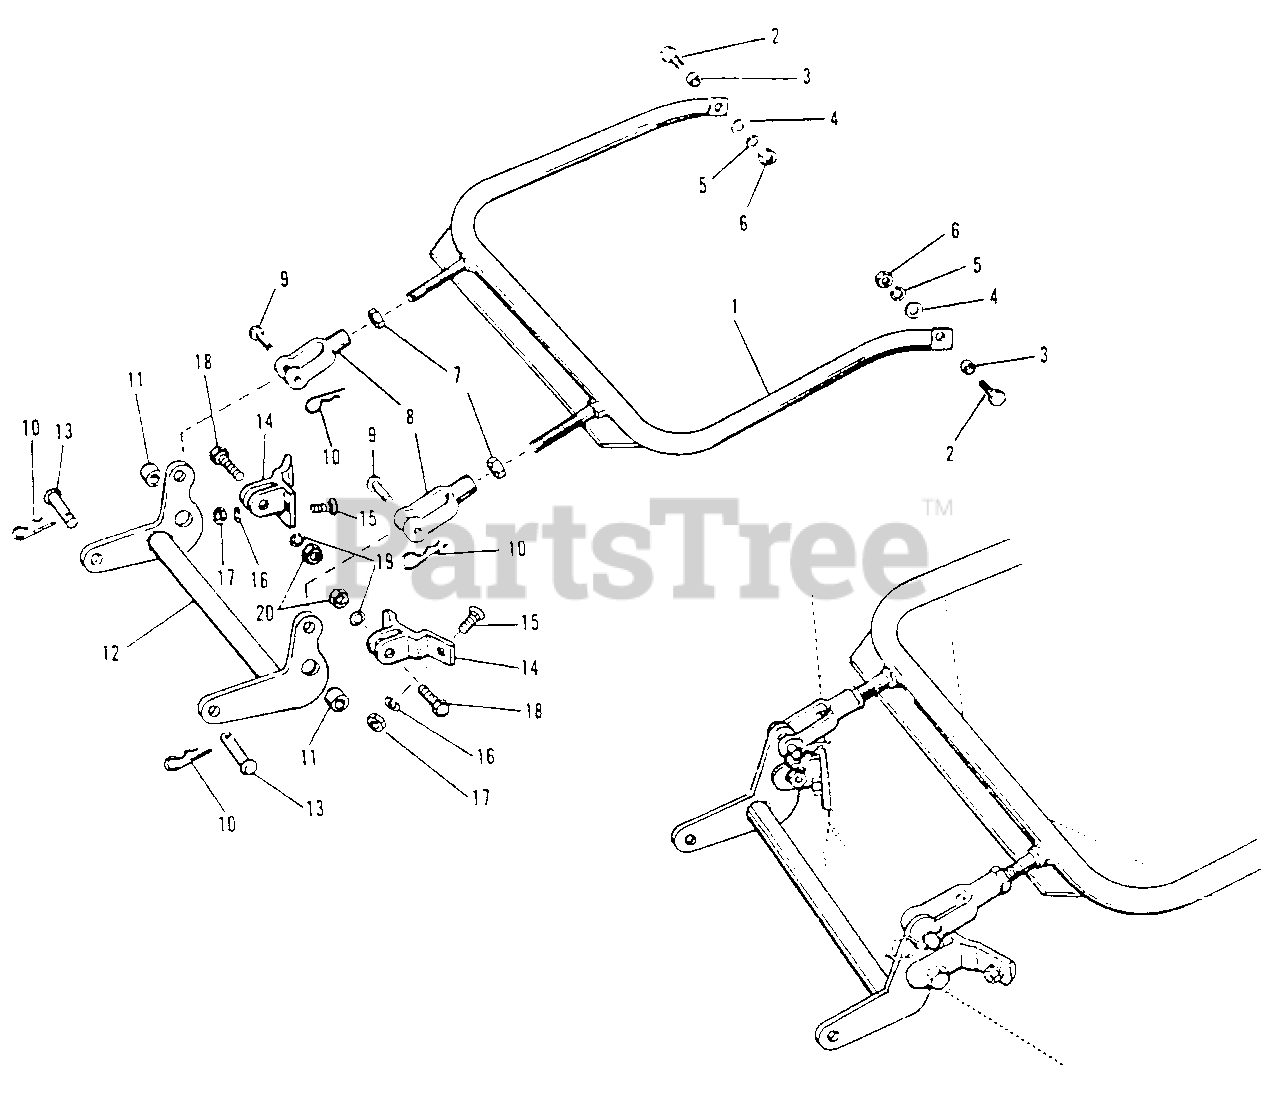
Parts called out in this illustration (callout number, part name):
1	Bail Assembly
2	Capscrew, Hex. Hd., 1/2"-13 NC x 1 1/4" lg.
4	Washer, Plain, 7/16
5	Washer, Lock, 1/2"
6	Nut, Hex., Full, 1/2"-13 NC
7	Nut, Hex., Jam, 1/2"-20 NF
8	Yoke End, Adjusting
10	Clip, Spring
12	Rocker Arm
13	Pin
14	Bracket Assembly, Front
15	Bolt, Carriage, 3/8"-16 NC x 1"
16	Washer, Lock, 3/8" .
17	Nut, Hex. Full, 3/8" 16 NC
18	Capscrew, Hex., 1/2"-13 NC x 1 1/4"
19	Washer, Lock, 1/2" V
20	Nut, Hex., Full, 1/2"-13 NC
